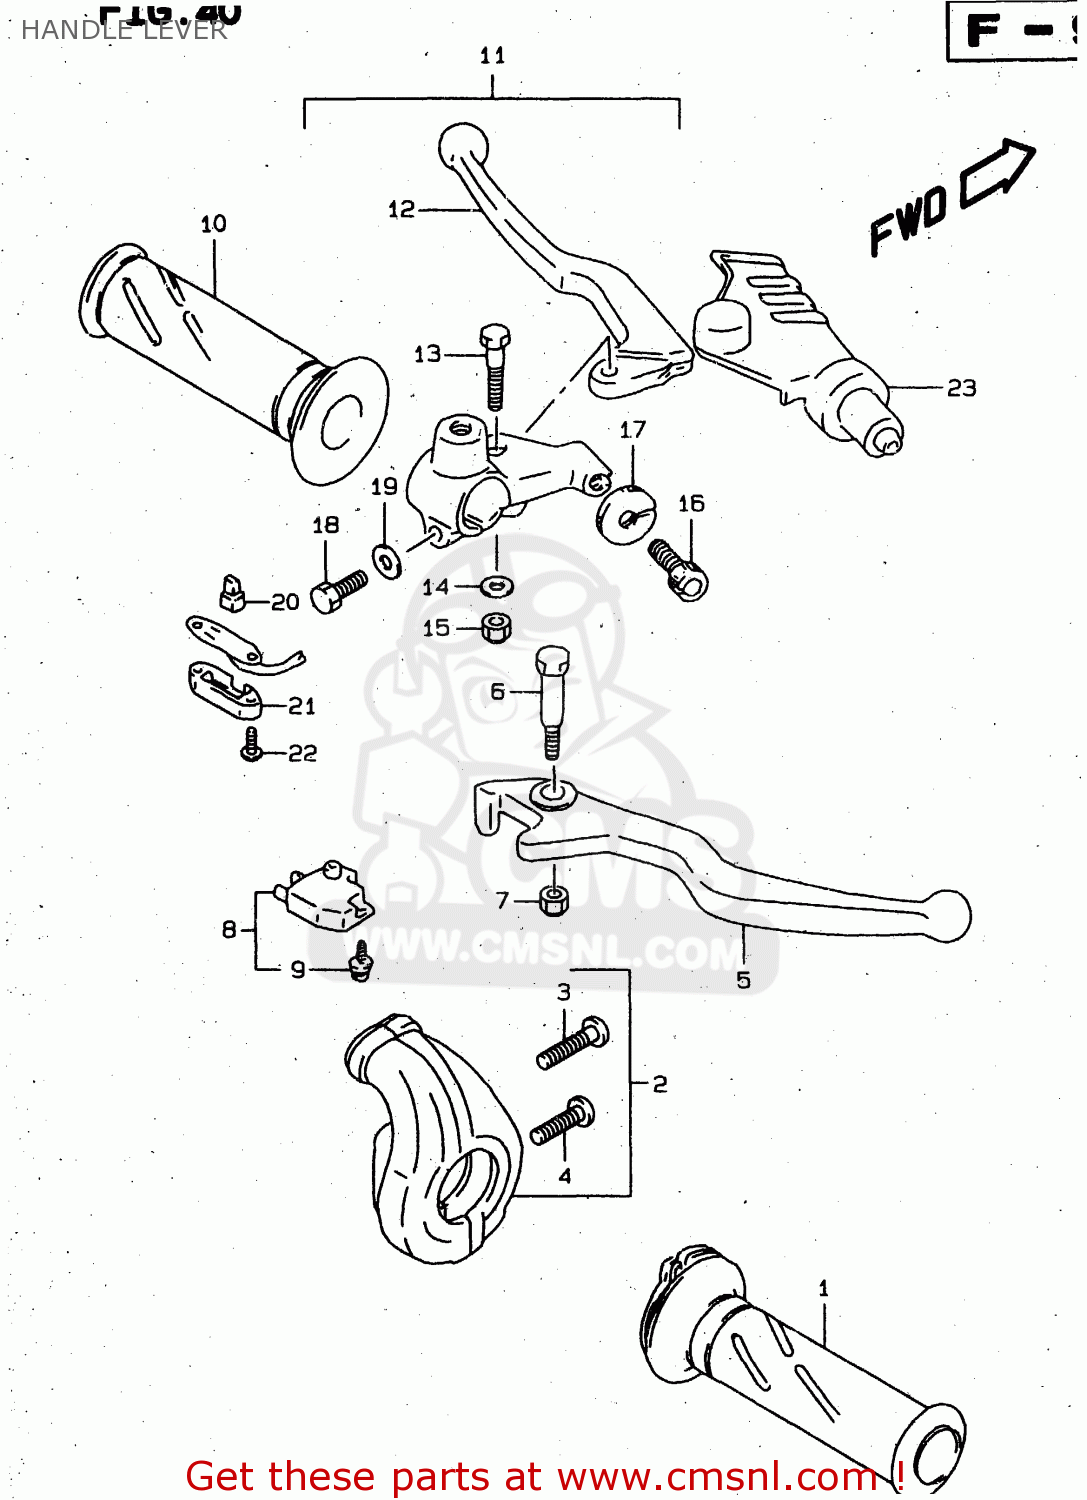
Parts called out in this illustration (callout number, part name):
1	GRIP,THROTTLE
2	CASE ASSY,THROTTLE
3	SCREW(5X25)
4	SCREW
5	LEVER,FR BRAKE
6	BOLT,BRAKE LEVER PIVOT
7	NUT,LEVER PIVOT
8	SWITCH ASSEMBLY,STOP
9	SCREW
10	GRIP,LEFT
11	LEVER ASSY,CLUTCH
12	LEVER,CLUTCH
13	BOLT,LEVER SET
14	WASHER
15	NUT,LEVER PIVOT
16	ADJUSTER,CABLE
17	NUT,CABLE ADJUSTER LOCK
18	BOLT
19	WASHER
20	CONTACT,SWITCH
21	COVER,FR BK TERMINAL BASE
22	SCREW
23	COVER,CLUTCH LEVER
